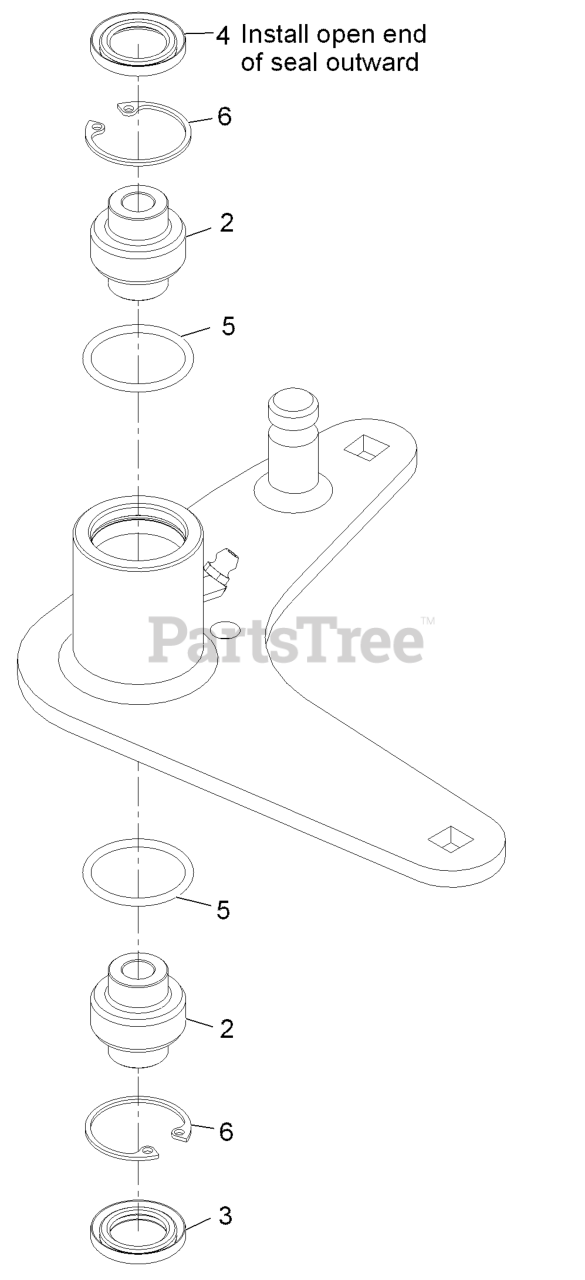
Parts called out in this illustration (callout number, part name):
2	Bearing-Spherical
3	Seal-Lip, Double
4	Seal-Single Lip
6	Ring-Retaining
